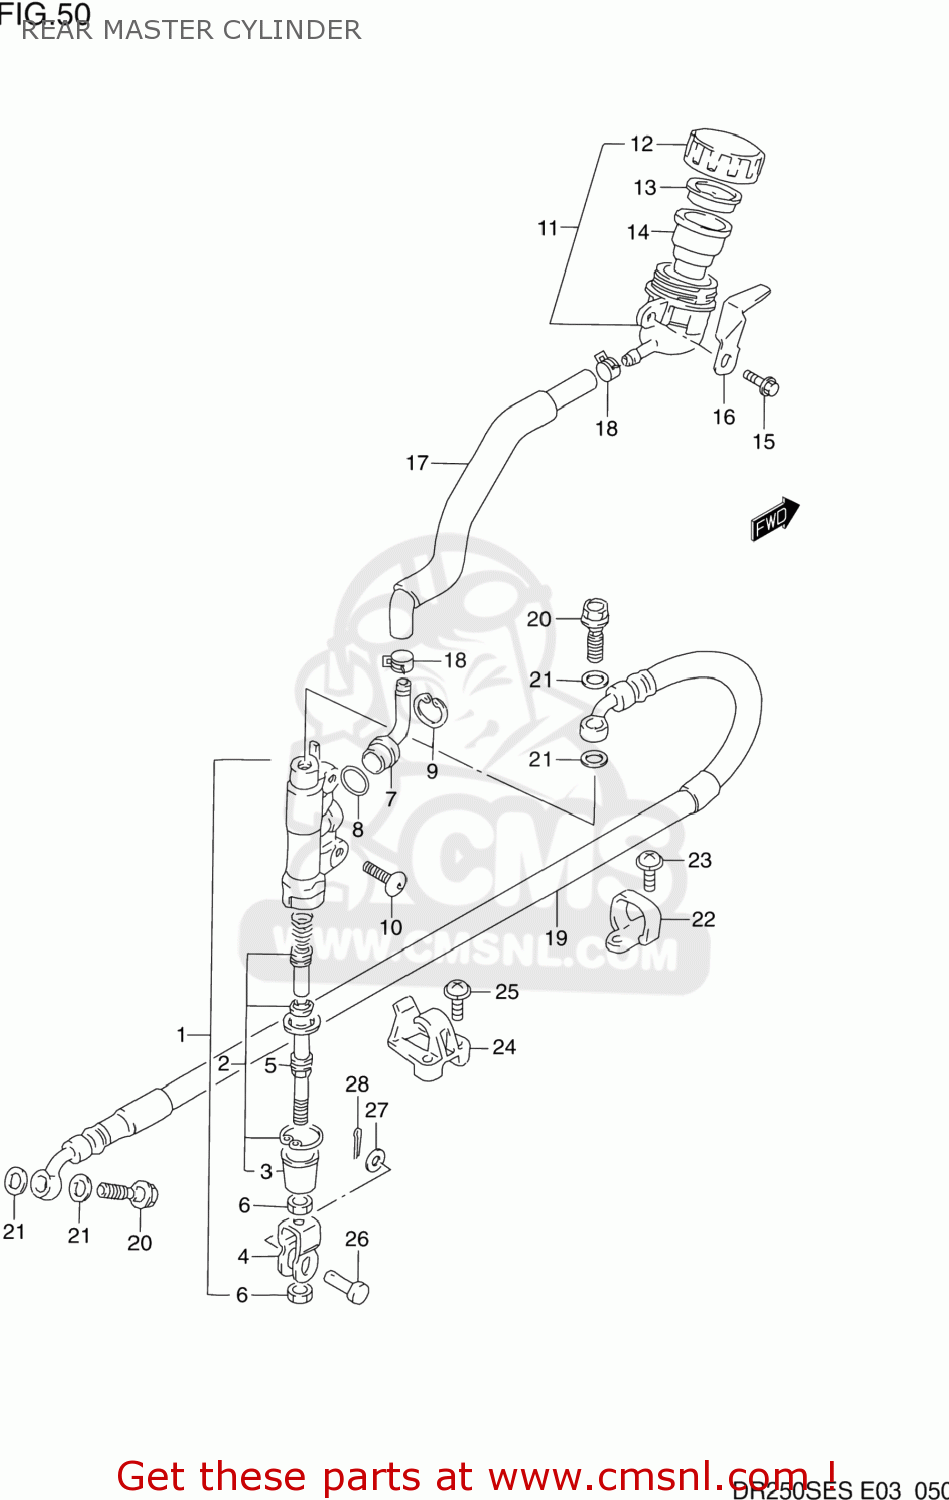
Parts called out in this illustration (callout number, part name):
1	CYLINDER ASSEMBLY,REAR MASTER
2	PISTON/CUP SET
3	BOOT
4	YOKE
5	ROD,PUSH
6	NUT
7	CONNECTOR
8	O RING
9	CIRCLIP
10	SCREW(6X16)
11	TANK ASSY,RR BRAKE RESERVOIR
12	CAP
13	PLATE
14	DIAPHRAGM
15	BOLT
16	GUARD,RSVR TANK CAP
17	HOSE COMP,RESERVOIR TANK
18	CLIP
19	HOSE,RR BRAKE
20	BOLT UNION
21	WASHER(10X15X1.5)
22	GUIDE,RR BRAKE HOSE
23	SCREW
24	GUIDE,RR BRAKE HOSE
25	SCREW
26	PIN(8X20)
27	WASHER(8.5X13X1.6)
28	PIN 20X15
